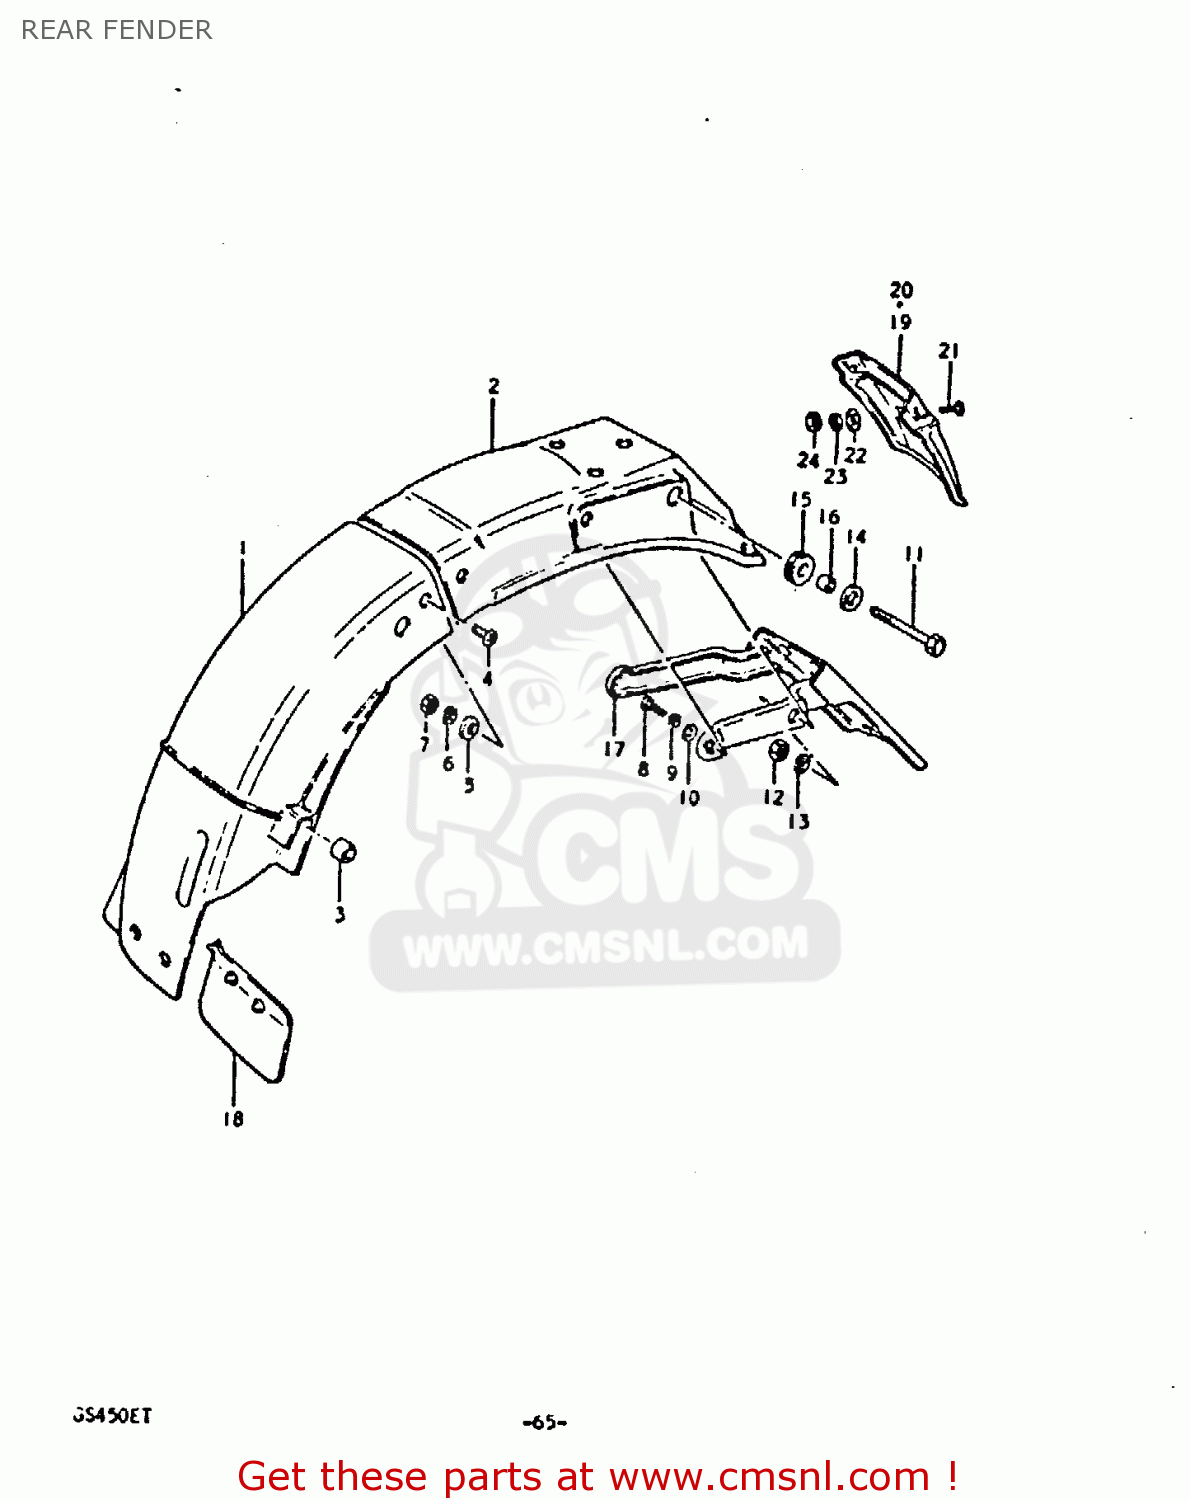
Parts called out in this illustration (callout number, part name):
1	FENDER,REAR
2	BODY,REAR FENDER,REAR
3	CUSHION
4	SCREW
5	WASHER (5.5X16X1.2)
6	LOCK WASHER
7	NUT
8	BOLT, UPPER
9	LOCK WASHER
10	WASHER
11	BOLT
12	NUT
13	LOCK WASHER
14	WASHER(8.5X26X1.2)
15	CUSHION
16	SPACER (8.2X12X7.5)
17	REINFORCEMENT,REAR FENDER
18	GUIDE,RR FENDER MUD
